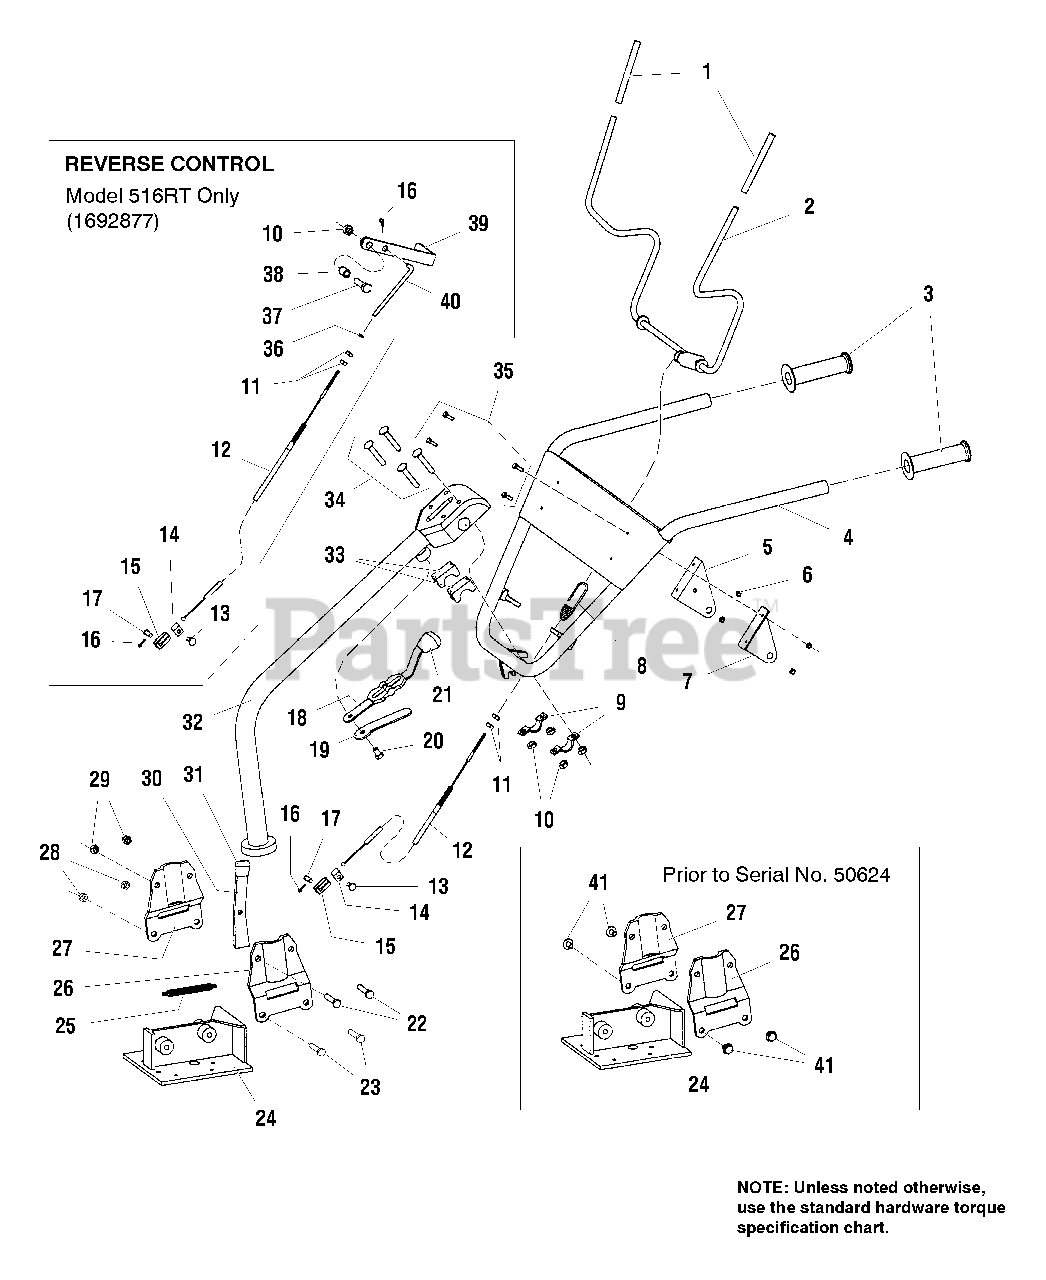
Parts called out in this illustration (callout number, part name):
1	HANDLE GRIP, Drive Control Lever
2	LEVER, Drive Control
3	HANDLE GRIP, Black
4	ASSEMBLY, Main Handlebar
5	BRACKET, Drive Control Lever, Right
6	NUT, Nyloc, 5mm x 0.8mm
7	BRACKET, Drive Control Lever, Left
8	SPRING, Forward Cable Adjust
9	CLAMP, Handlebar Tilt
10	NUT, 5/16"-18
11	NUT, Jam, 5/16"-24
12	CABLE ASSEMBLY, Control Engage
13	BOLT, Hex Hd, 1/4"-20 x 1/2"
14	CLAMP, Cable
15	YOKE, Cable
16	COTTER PIN
17	PIN, Link
18	LEVER, Handlebar Tilt
19	STOP, Handlebar Tilt Lever
20	BOLT, 8mm x 16mm
21	KNOB, Handlebar Tilt Lever
22	BOLT, 10mm x 30mm
23	BOLT, Hex Hd, 5/16" - 18 x 2-3/4", Grade 5
24	COVER, Transmission Wheel Housing
25	SPRING, Handlebar Swivel
26	MOUNT, Handlebar Stem, Left
27	MOUNT, Handlebar Stem, Right
28	NUT, Bi-way Lock, 5/16"-18
29	NUT, Nyloc, 10mm
30	LEVER, Handlebar Swivel
31	KNOB, Handlebar Swivel Lever
32	HANDLEBAR STEM
33	TILT FRICTION PAD
34	BOLT, Carriage Hd, 5/16"-18 x 2"
35	BOLT, Hex Hd, 5mm x 0.8mm x 10mm
36	NUT, Nyloc, #10
37	CAPSCREW, Hex Head 5/16-18 x 2 G5
38	BUSHING, Pivot, 5/16"
39	REVERSE HANDLE
40	REVERSE LINK
41	BOLT, Hex Flange Hd, 5/16"-18 x 1/2", Grade 5 (Prior to Serial No. 50624)
